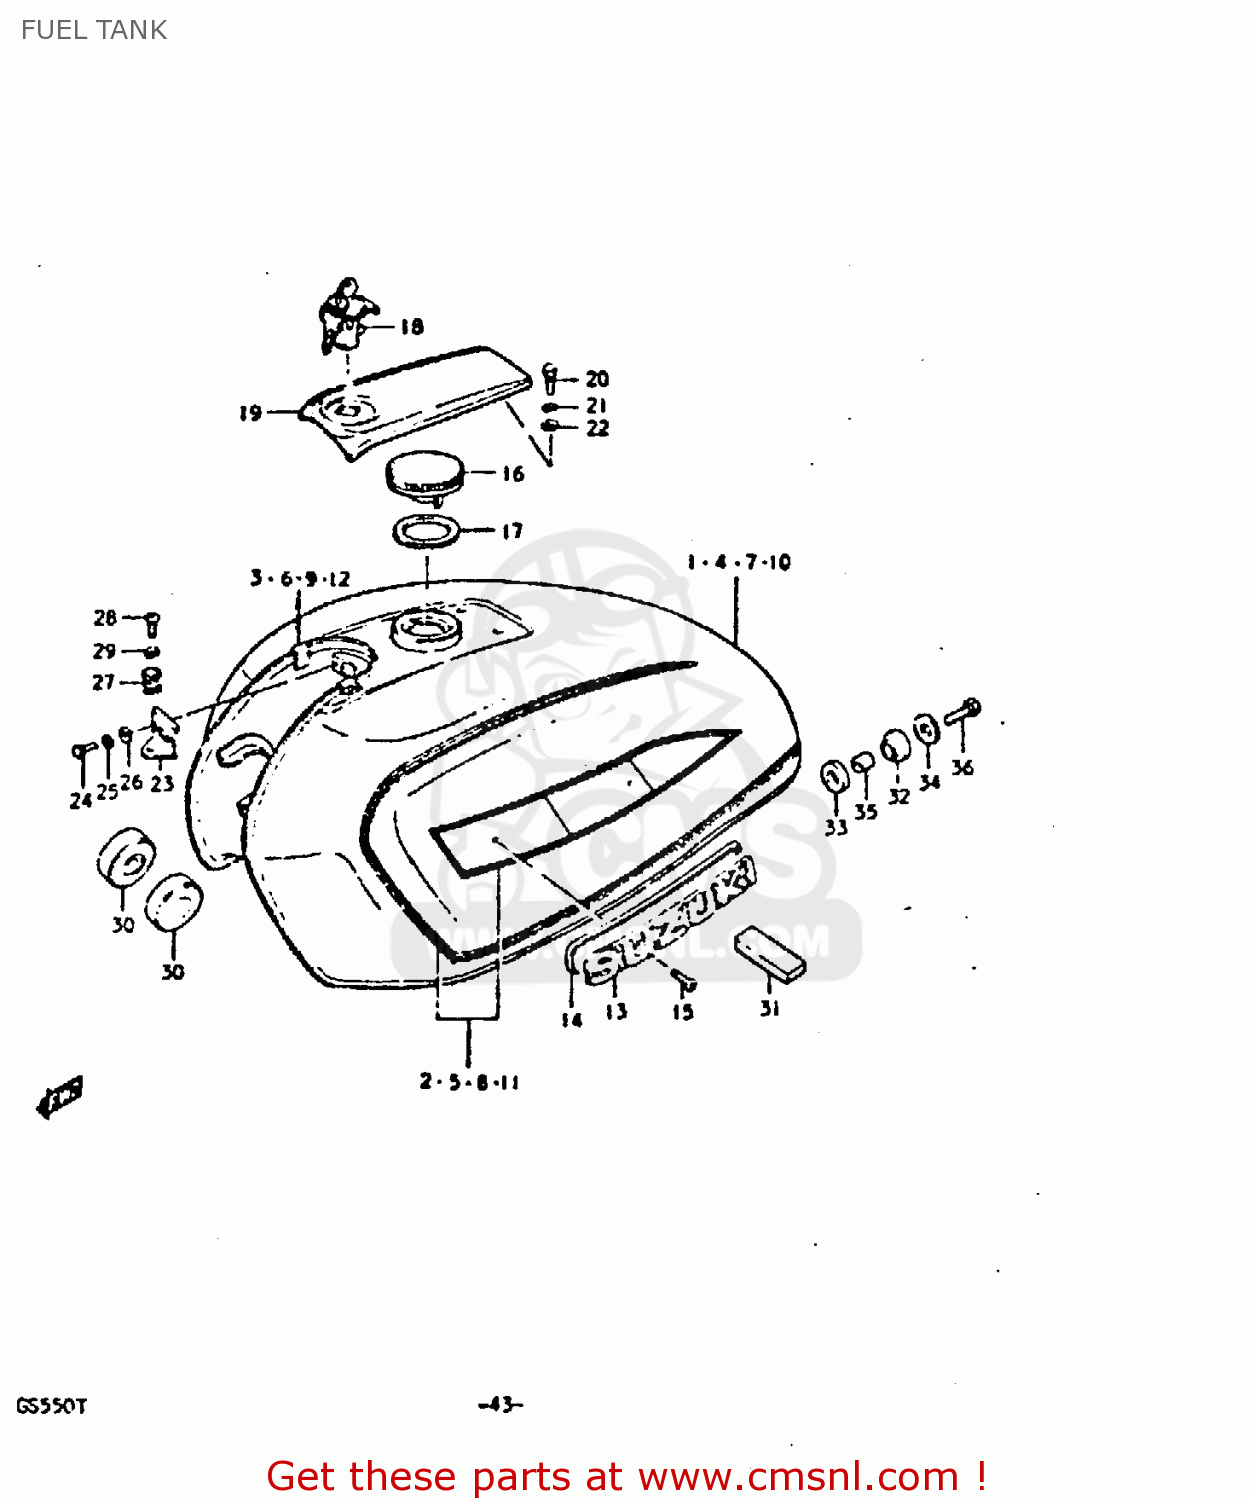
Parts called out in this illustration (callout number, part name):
1	TANK, FUEL
2	TAPE SET
3	CUSHION,FUEL TANK FR COVER
4	TANK, FUEL
5	TAPE SET
6	CUSHION,FUEL TANK FR COVER
7	TANK, FUEL
8	TAPE SET
9	CUSHION,FUEL TANK FR COVER
13	EMBLEM,FUEL TANK
15	SCREW 3X6
16	CAP ASSY,FUEL TANK FILLER
17	GASKET (NAS)
18	LOCK,FUEL TANK FR COVER
19	COVER,FUEL TANK,FRONT
20	BOLT
21	LOCK WASHER
22	WASHER
23	HOLDER,FUEL TANK FRONT COVER
24	BOLT
25	LOCK WASHER
26	WASHER
27	SPRING
28	SCREW
29	LOCK WASHER
30	CUSHION
31	CUSHION
32	CUSHION
33	CUSHION
34	WASHER (8.5X29X1.6)
35	SPACER(8.5X12X19)
36	BOLT (8X30)
